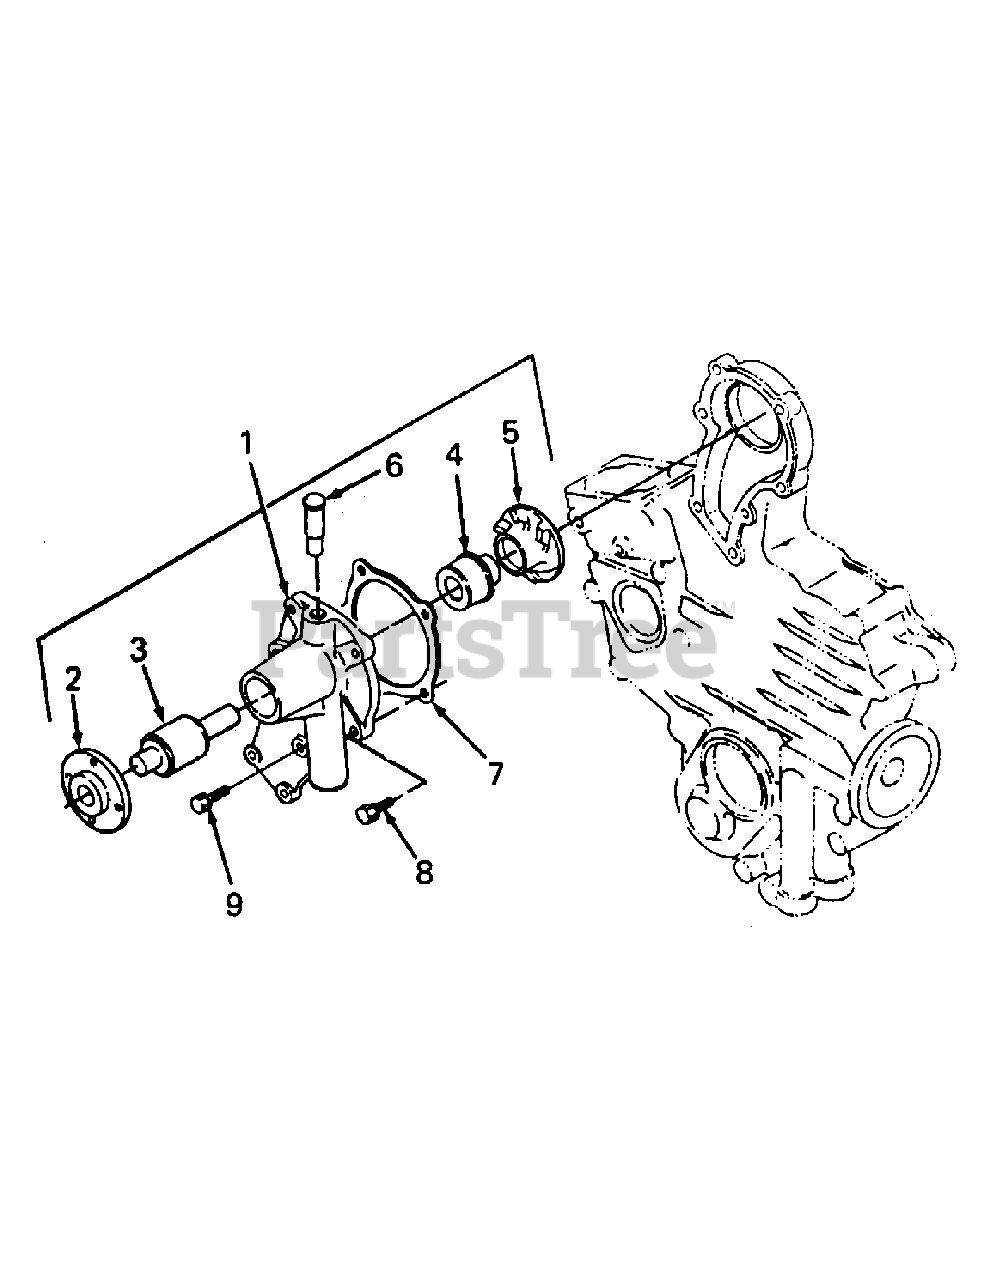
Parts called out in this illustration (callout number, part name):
2	Flange, Water Pump
3	Bearing, Ball
4	Mechanical Seal Assy
5	Impeller, Water Pump
6	Pipe, Water Return
7	Gasket, Water Pump
